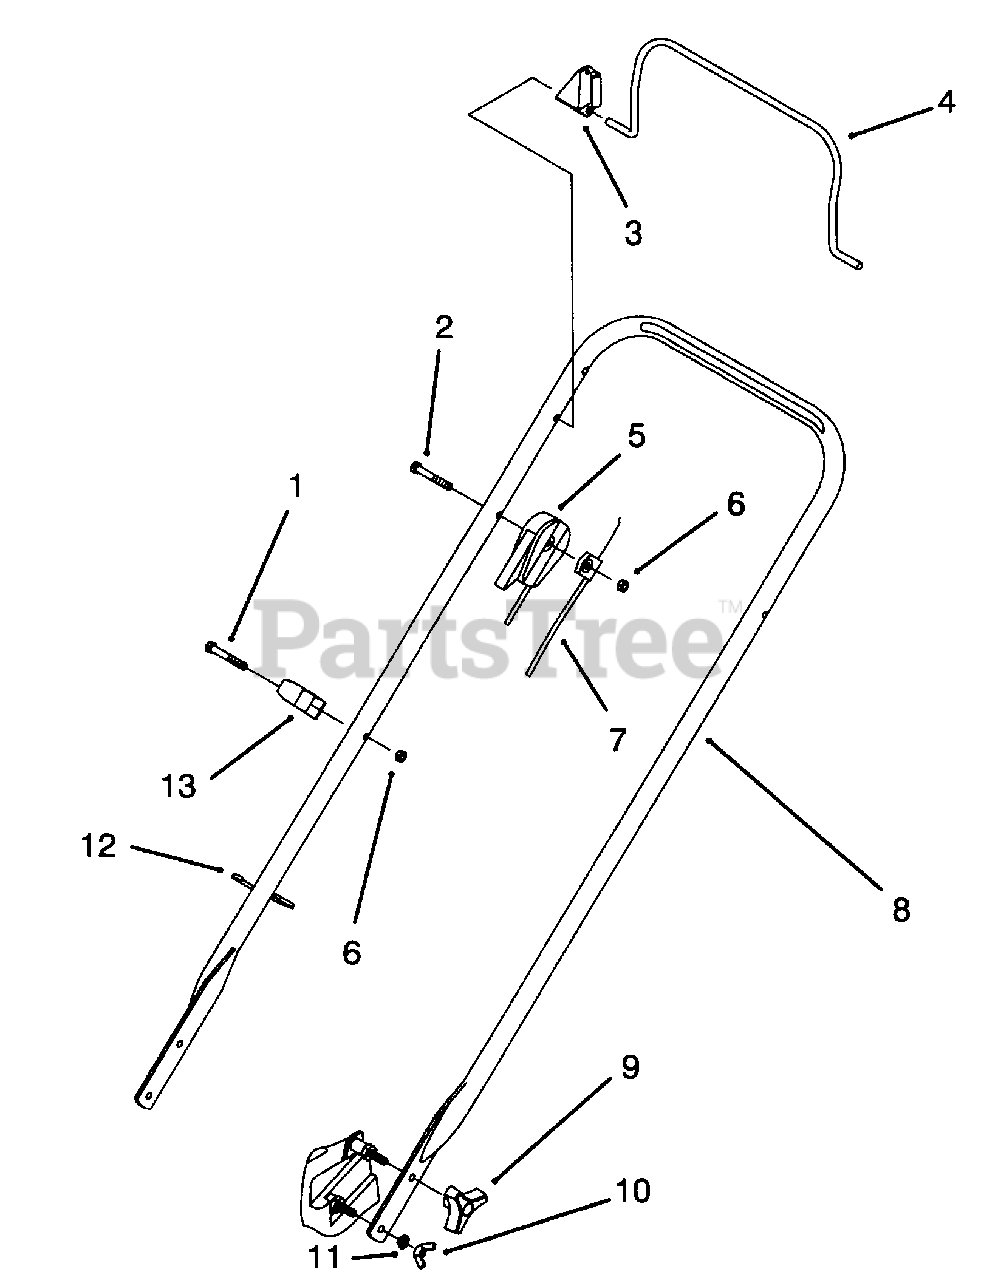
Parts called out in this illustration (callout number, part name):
1	Screw-Hex Hd. Cap
2	Screw-Hex Hd. Cap
3	Stop-Pivot
4	Bail-Flywheel Brake
5	Cable-Throttle
6	Nut-Lock
7	Cable-Flywheel Brake
9	Knob
11	Washer-Lock
12	Tie-Cable
13	Guide-Rope
